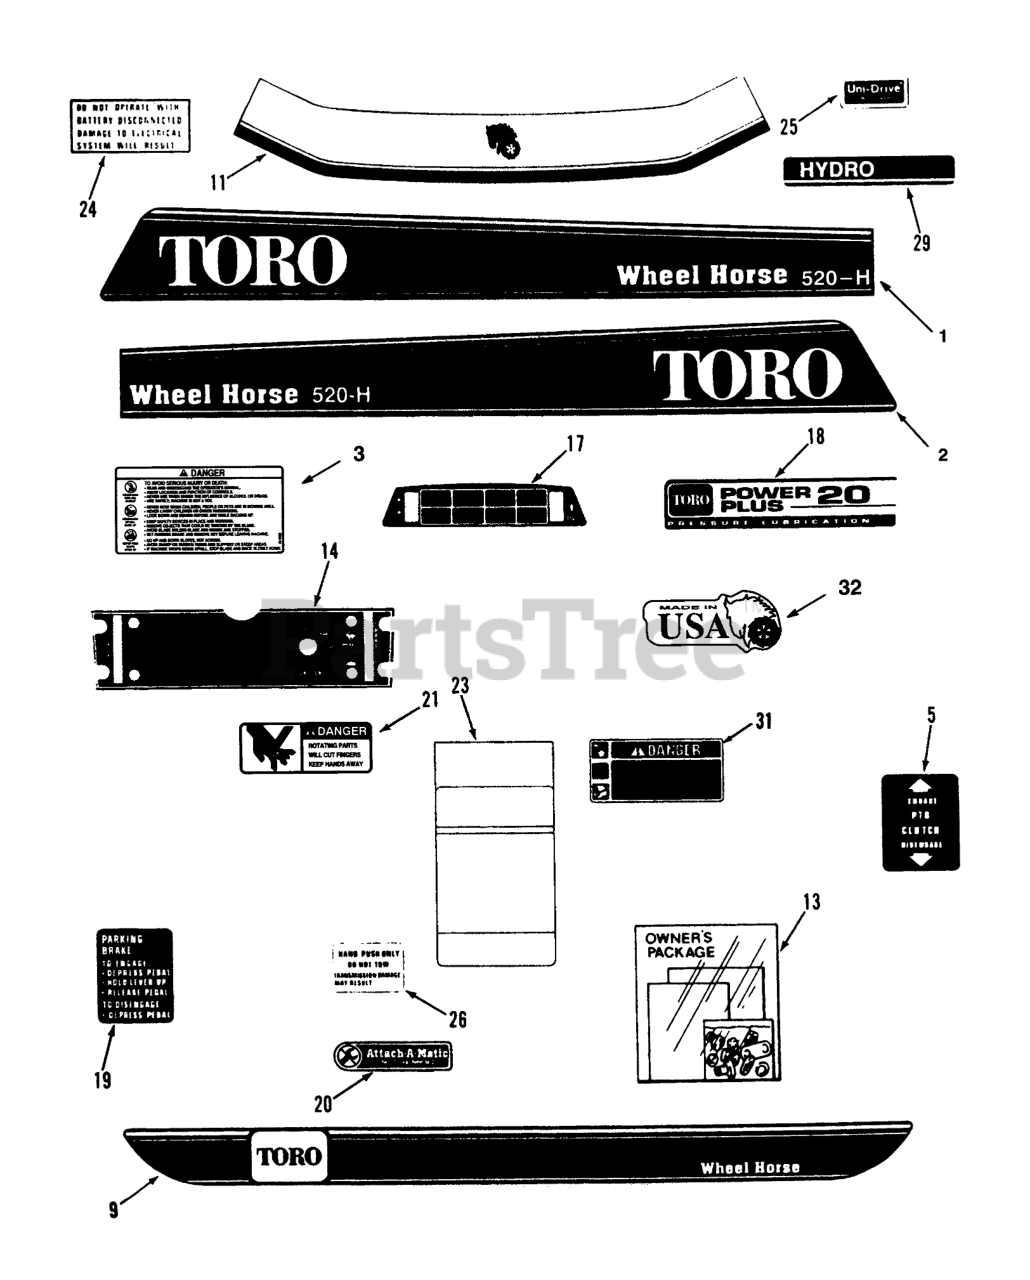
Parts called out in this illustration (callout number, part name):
1	DECAL HOOD 520H, RH
2	DECAL HOOD 520H, LH
3	DECAL - DANGER
5	DECAL PTO CLUTCH
9	DECAL-FENDER
11	DECAL-FRONT HOOD
13	ASS'Y-LOOSE PARTS PK
14	DECAL-FRONT PANEL
17	DECAL-IND LIGHTS
18	DECAL-PWR PLUS 20 PL
19	DECAL-PARKING BRAKE
20	Decal-Attac-O-Matic
21	DECAL - DANGER
23	Decal-Maintenance
24	DECAL ELECT SYSTEM
25	Decal-Unidrive
26	DECAL-DO NOT TOW
29	DECAL-MODEL HYDRO
31	DECAL-DANGER
32	DECAL - USA
